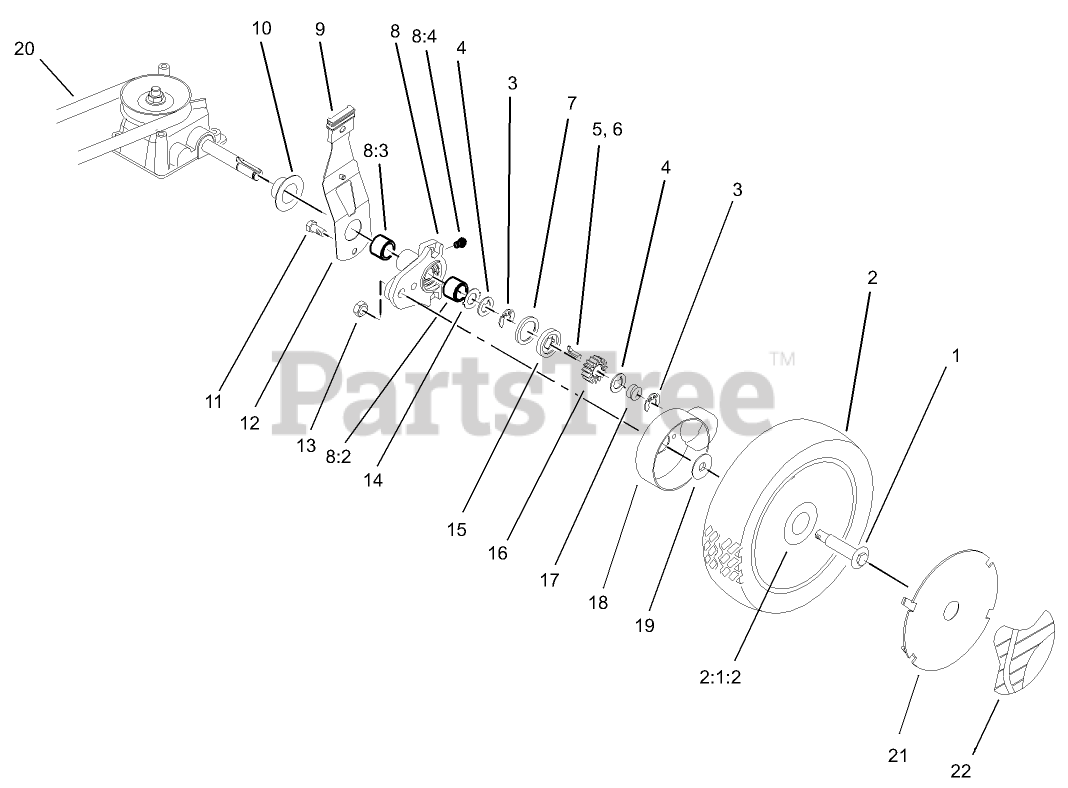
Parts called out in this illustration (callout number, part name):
1	BOLT-SHOULDER
2	WHEEL ASM
2:1:2	BUSHING
3	RING-RETAINING,CLIP
4	WASHER-THRUST, KEYED
5	KEY-ROCKING, RH
6	KEY-ROCKING, LH
7	RING-FRICTION
8	PIVOT ARM ASM
8:2	BUSHING
8:3	BUSHING
8:4	FITTING-GREASE
9	KNOB-ARM
10	CAP-END
11	SCREW-HWH
12	SPRING ARM ASM
13	LOCKNUT
14	WASHER-ARM, PIVOT
15	WASHER-CLUTCH
16	GEAR-PINION
17	SPRING-COMPRESSION
18	COVER-WHEEL
19	SPACER-COVER, WHEEL
20	BELT-V
21	COVER-WHEEL
22	LABEL-WHEEL, SMART
